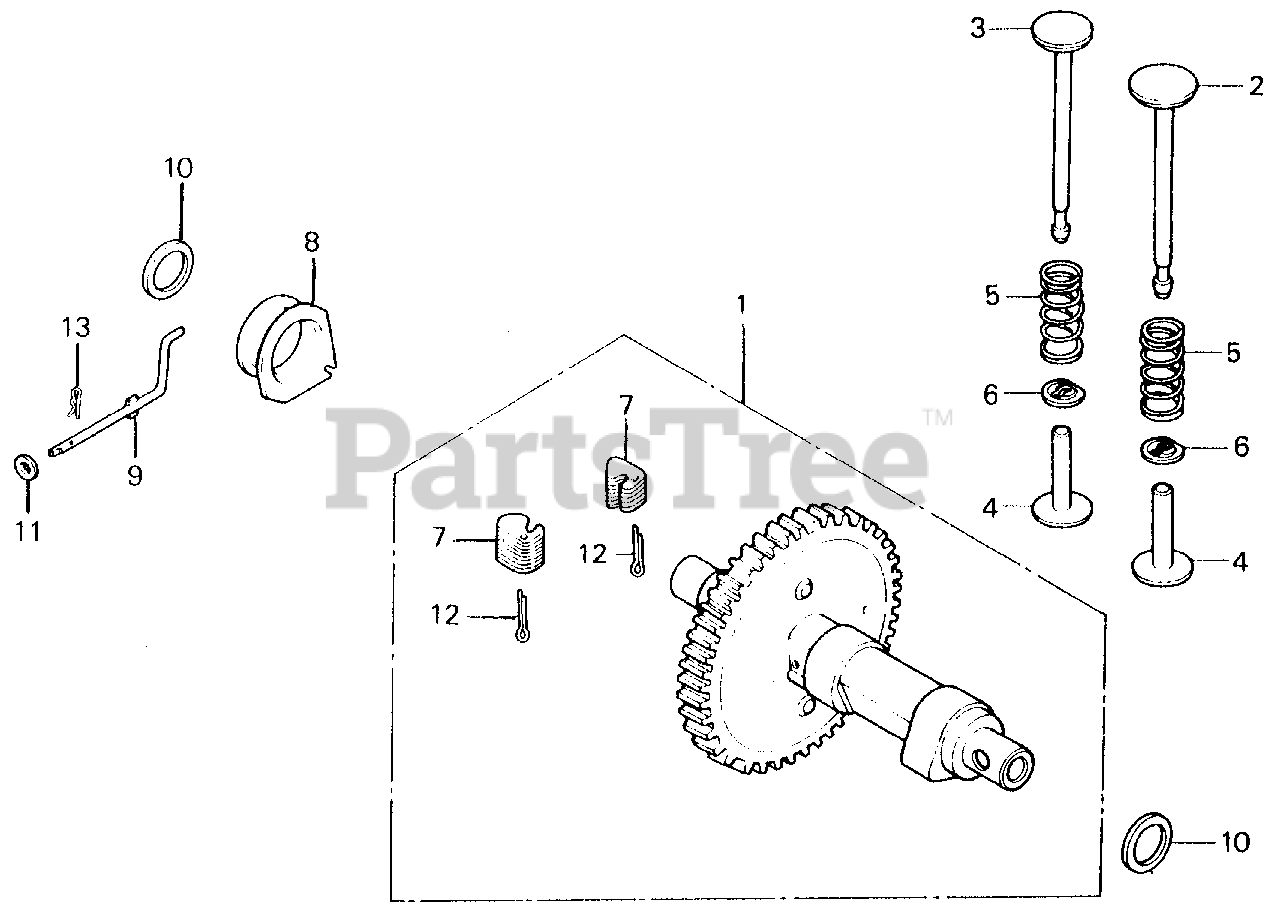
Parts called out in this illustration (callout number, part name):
1	CAMSHAFT ASSY.
2	VALVE, IN.
3	VALVE, EX.
4	LIFTER, VALVE (39.6MM)
4	LIFTER, VALVE (39.9MM)
5	SPRING, VALVE
6	RETAINER, VALVE SPRING
7	WEIGHT, GOVERNOR
8	SLIDER, GOVERNOR
9	SHAFT, GOVERNOR ARM
10	WASHER, THRUST (18MM)
11	WASHER, PLAIN (5MM)
12	PIN, COTTER (3.0X45)
13	PIN, LOCK (8MM)
